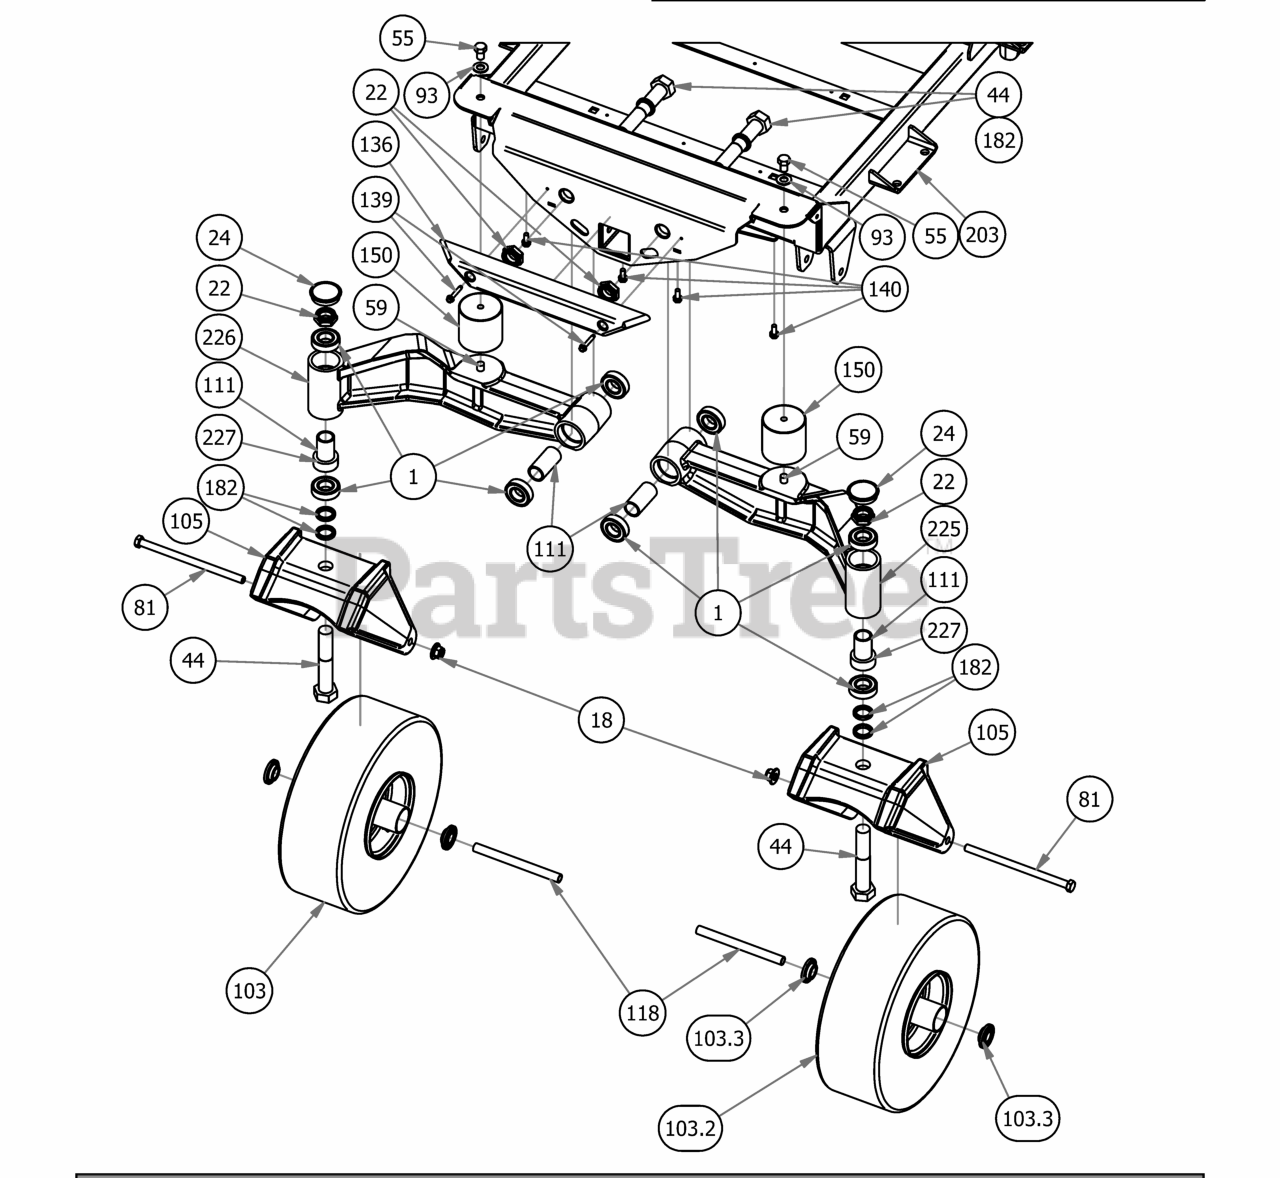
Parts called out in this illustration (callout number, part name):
1	1641 BEARING W/2 CONTACT RUBBER SEALS
18	1/2-13 NYLON INSERT FLANGE LOCKNUT ZINC
22	1" Fine Thread 1/2 Nylock Nut
24	2017 Bearing Cover
44	1-14 x 5.5 Hex Bolt Grade 8 Zinc Yellow
55	1/2" x 3/4" Hex Bolt
59	1/2-13 x 1" Stud
81	1/2" x 9" GR 5 Hex Bolt
93	1/2" Washer (Grade 8)
103	2019 15x6.00-6 Non Pneumatic Black Front Assembly
103.2	15x600-6 Tire Only
103.3	1-3/4" Bearing-Large Bore Front Rim
105	2019 Rebel, Rogue, Renegade Front Fork
111	2016 Front Bearing Spacer
118	Front Wheel Spanner
136	2017 XP Bumper
139	1/4" x 1 1/2" Self Tapping Screw
140	5/16 x 3/4 washer head type F screw
150	Vibration Mount-Blue Dot
182	Spacer, 1x1.375x.25
203	2019 Horizontal Gas Frame
225	2019 Front I-Beam Left
226	2019 Front I-Beam Right
227	Rubber Stabilizer (Front Forks) [R series]
